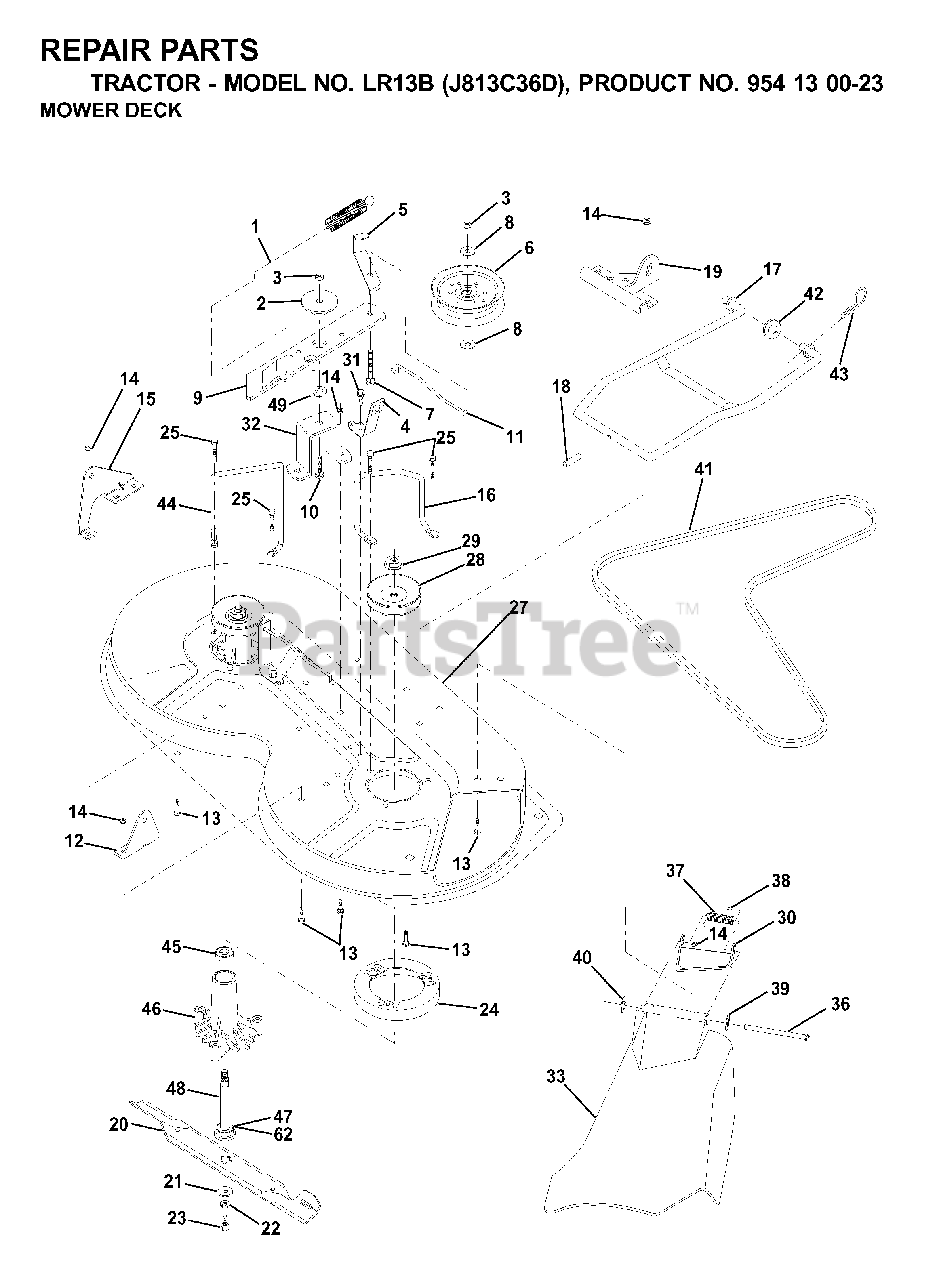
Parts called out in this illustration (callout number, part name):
1	SPRING-MOWER CLUTCH
2	SPACER.RETAINER.MOWER
3	LOCKNUT
4	BRAKE ASSEMBLY
5	IDLER BELT GUIDE
6	PULLEY IDLER
7	BOLT
8	WASHER
9	IDLER ARM ASSY
10	BOLT.3/8-14X1.25
11	BRAKE ROD
12	BRKT LIFT REAR
13	BOLT
14	LOCKNUT
15	BRKT LIFT REAR LH
16	BELT KEEPER
17	MOWER LINK STABILIZER
18	PIN GROOVE
19	BRKT LINK STABILIIZER
21	WASHER.BLADE
22	LOCKWASHER
23	BLADE BOLT
24	STRIPPER
25	SCREW THDROL ROLLING WASHER HD
27	MOWER HOUSING
28	PULLEY, MANDREL
29	NUT
30	BRACKET ASM DEFLECTOR
31	SCREW LT
32	SUPT,IDLER ARM
36	HINGE ROD
37	SPRING TORSION
38	CAP-SLEEVE LT
39	WASHER
40	NUT PUSH M
42	WASHER
43	SPRING RETAINER
44	KEEPER LH
46	HSG MANDREL
47	BEARING
48	SHAFT ASM VENT
49	HARDENED WASHER
62	WASHER FELT
